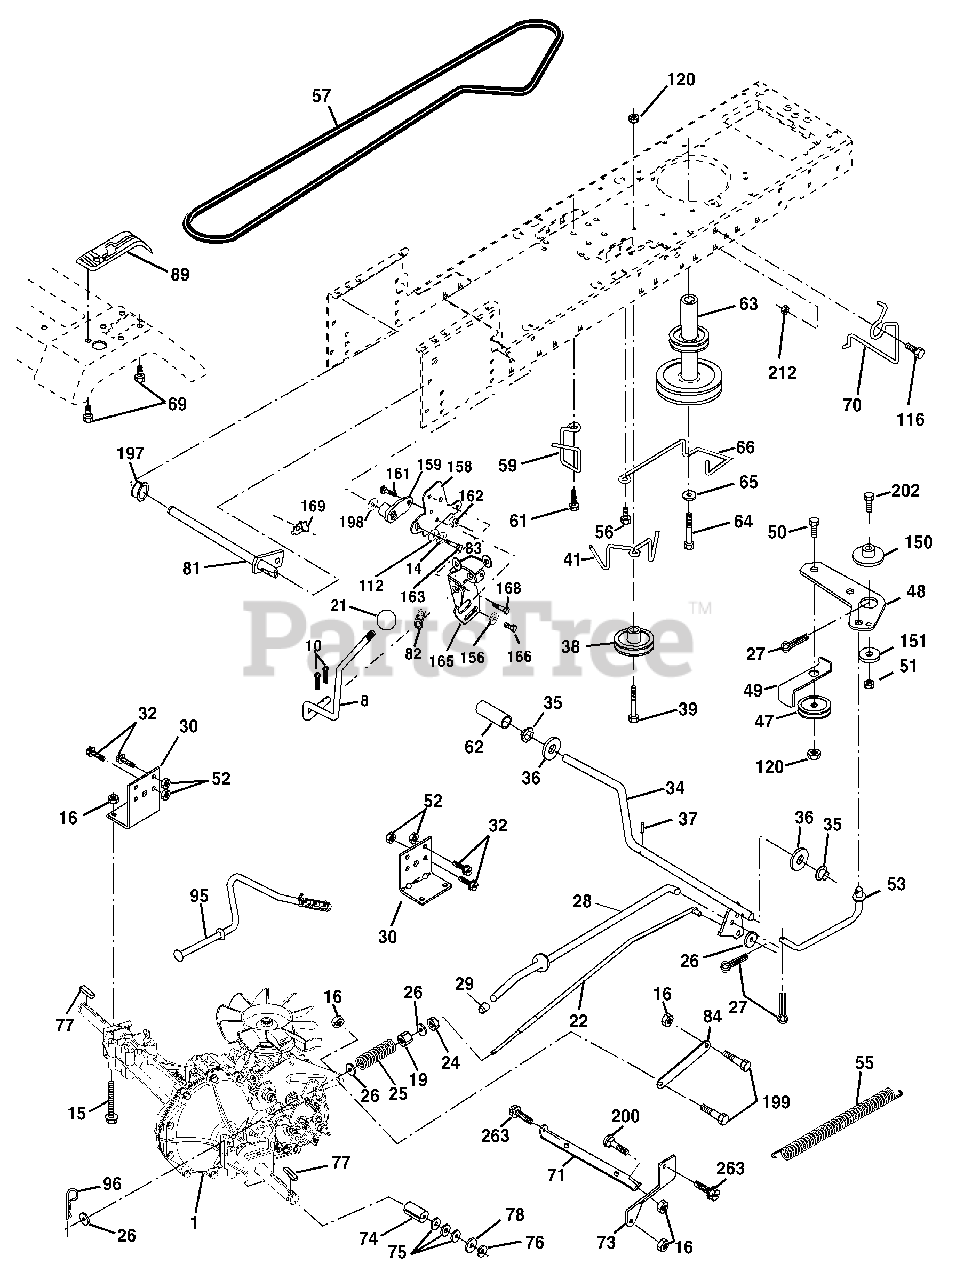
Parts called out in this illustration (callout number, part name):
8	Rod Shift Hydro LT
10	Pin Cotter 1/8 x 1 CAD
14	Washer Lock Hvy Helical
15	Bolt, Hex FLGHD 5/16-18 Gr. 5
16	Nut Lock Hex W/Ins 5/16-18unc P
19	Nut Lock Hex W/Wsh 3/8-16 unc
21	Knob, Round 1/2-13
22	Rod, Brake Hydro
24	Nut
25	Spring, Brake Rod
26	Washer
27	Pin Cotter 1/8 x 3/4 CAD.
28	Rod, Parking Brake
29	Cap, Parking Brake
30	Bracket, Transaxle
32	Bolt Hex Hd 5/16-18 unc x 3/4
34	Shaft, Foot Pedal
35	Bearing, Nylon
36	Washer
37	Pin, Roll
38	Pulley, Flat Composite
39	Bolt RDHD 3/8-16 unc x 2-3/4 Gr. 5
41	Keeper, Belt Idler
47	Pulley, Idler, V-Groove
48	Bellcrank Clutch Grnd Drv STL
49	Retainer, Belt
50	Bolt Carr. SH 3/8-16 x 1-1/2 Gr. 5
51	Nut Crownlock 3/8-16 unc
52	Nut Crownlock 5/16-18 unc
53	Link, Clutch
55	Spring, Return, Clutch
56	Screw 3/8-16 x 1-1/4
57	V-Belt, Ground Drive
59	Keeper, Center Span
61	Screw 3/8-16 x .875
62	Cover, Pedal
63	Pulley, Engine
64	Bolt, Hex
65	Washer
66	Keeper Belt Engine
69	Screw
70	Guide Belt
71	Strap Torque Lh Hydro
73	Strap Torque Rh Hydro
74	Spacer, Axle
75	Washer 25/32 x 1-1/4 x 16 Ga.
76	E-Ring
77	Key, Square
78	Washer 25/32 x 1-5/8 x 16 Ga.
81	Shaft Asm. Cross Hydro
82	Spring Torsion T/A
83	Washer 17/32 x 3/4 x 16 Ga.
84	Link Transaxle
89	Console, Hydro
95	Control Asm Bypass Hydro
96	Retainer Spring 1" Zinc/Cad
112	Washer 9/32 x 3/4 x 10 Ga.
116	Bolt Rdhd Sq Neck 3/8-16 x 1
120	Nut Lock Flg 3/8-16
150	Spacer Retainer
151	Washer 13/32 x 2 x 10 Ga.
156	Washer Srrted 5/16 ID x 1.125
158	Bracket Shift Mount
159	Hub Tapered Flange Shift Lt
161	Bolt Rdhd Sqnk 1/4-20 x 3/4 Gr. 5
162	Nut Crownlock 1/4-20 unc
163	Bolt Hex Fin 1/4-20 unc x 1 Gr. 5
165	Bracket Pivot Lever
166	Screw 5/16-18 x 5/8
168	Bolt Shoulder 5/16-18 x .561
169	Plate Fastening Lt
197	Nyliner Snap-In 5/8" ID
198	Washer Nyl 7/8 ID x .105
199	Bolt Shoulder 5/16-18 unc
200	Bolt Rdhd Sqnk 5/16-18 unc x 1
202	Bolt RDHD 3/8-16 x 1-3/4 Gr. 5
212	Nut Hex Flg Lock
263	Screw Thdrol. 3/8-16 x .75
